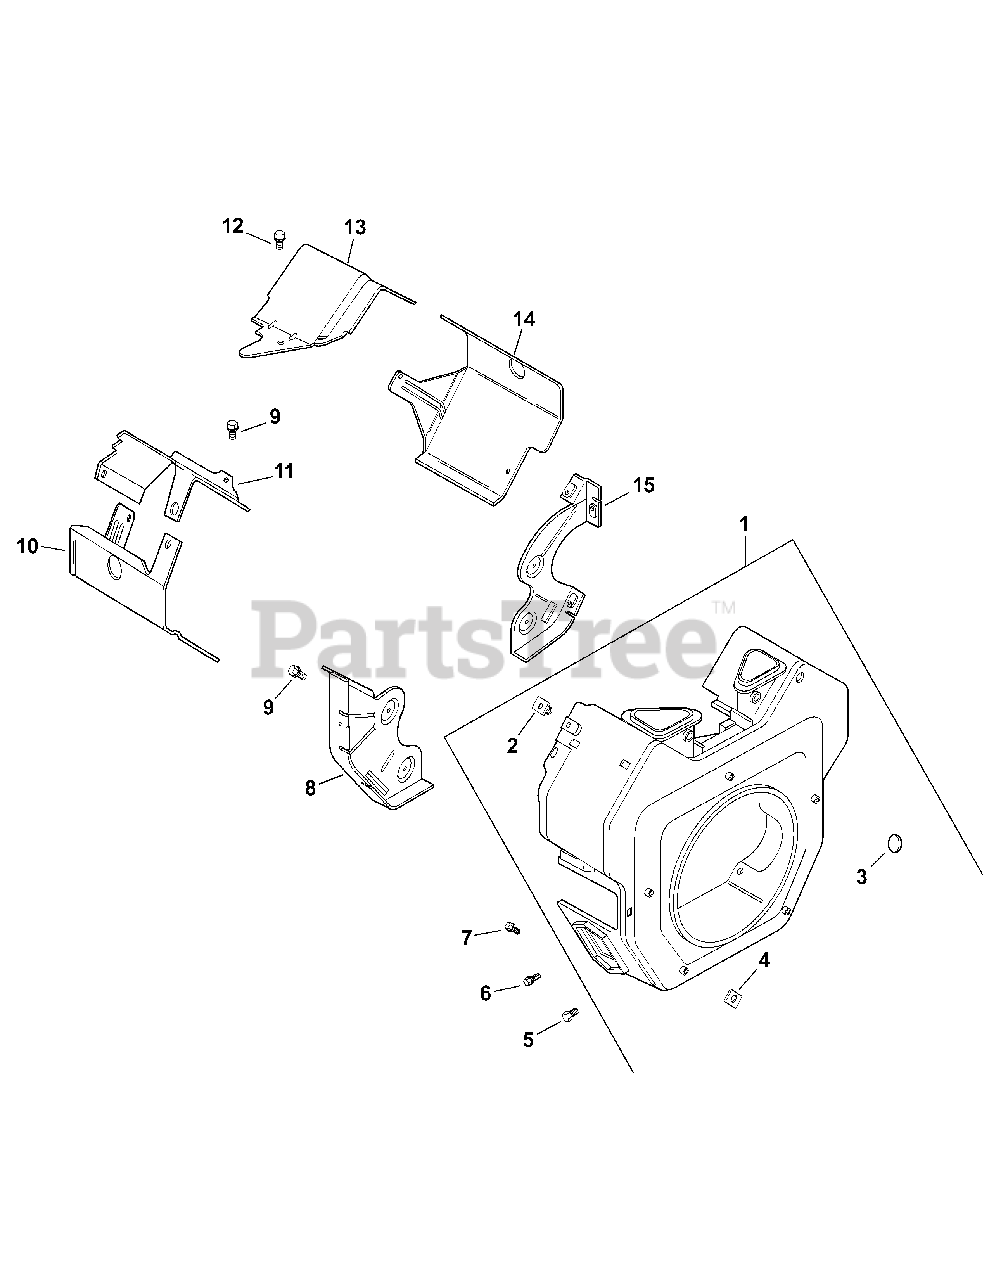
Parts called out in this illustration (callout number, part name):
1	Housing, blower (Includes 2-4)
2	Nut, plastic (3)
3	Plug, button
4	Nut, plastic (2)
5	Screw, hex. flange M5x0.8x16
6	Screw, hex. flange M5x0.8x16 (3)
7	Screw, hex. flange M5x0.8x20 (4)
8	Plate, backing - #2 side
9	Screw, hex. flange M6x1.0x16 (6)
10	Baffle, cylinder barrel - #2 side
11	Baffle, valley - #2 side
12	Screw, hex. flange M5x0.8x10 (2)
13	Baffle, valley - #1 side
14	Baffle, cylinder barrel - #1 side
15	Plate, backing - #1 side
